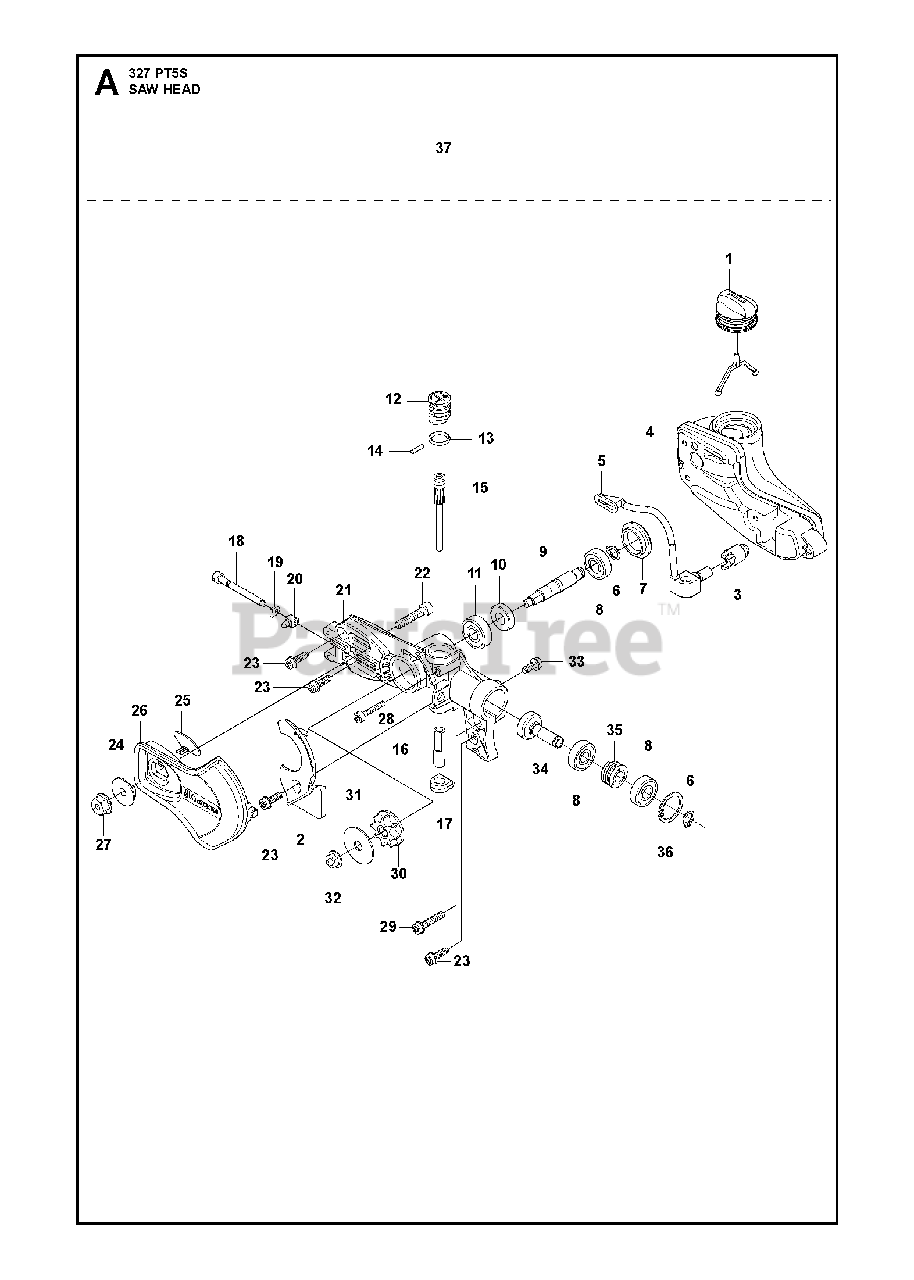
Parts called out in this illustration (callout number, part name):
1	RP TANK CAP ASSY
2	COVER
3	OIL SCREEN
4	OIL TANK
5	OIL HOSE
6	RETAINING RING
7	COVER
8	BALL BEARING
9	SHAFT
10	GEAR WHEEL
11	BALL BEARING
12	KNOB
13	O-RING
14	NEEDLE ROLLER
15	%PUMP PISTON
16	PUMP CYLINDER
17	FASTENER
18	SCREW
19	NUT
20	PAWL
21	GEAR HOUSING
22	SCREW IHSCM
23	SCREW
24	BUSHING
25	RUBBER
26	COVER
27	HEXAGON NUT FLANGED
28	SCREW ITXSCM
29	SCREW
30	SPUR SPROCKET
31	WASHER
32	FLANGE NUT
33	SCREW
34	PINION
35	WORM GEAR
36	RETAINING RING
37	POLE SAW HEAD
